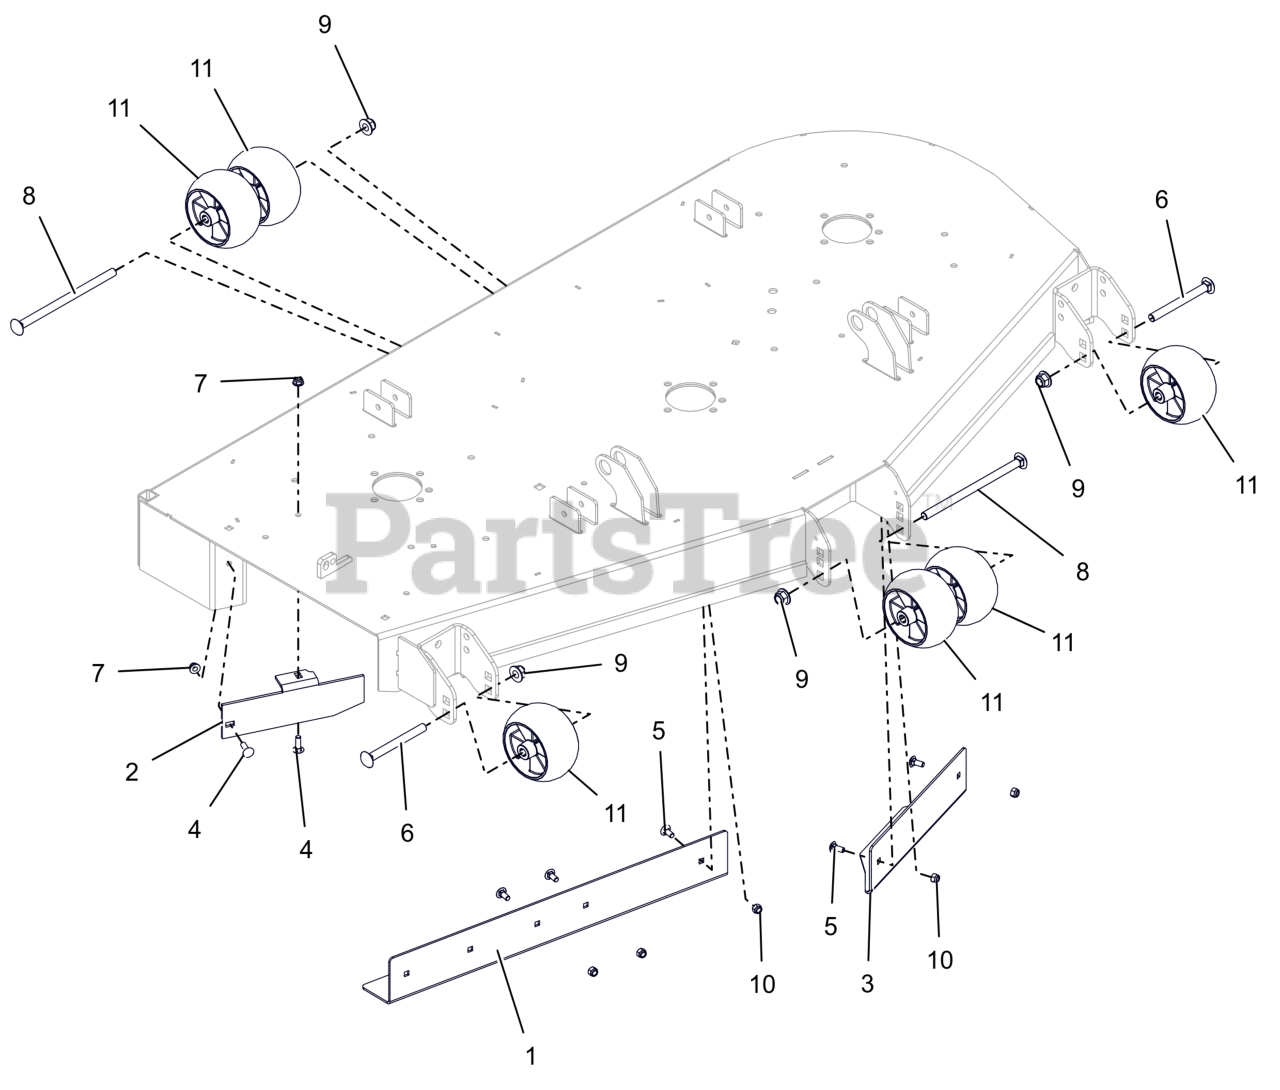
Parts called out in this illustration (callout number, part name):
1	BAFFLE, 60" RH VACUUM (RED)
2	60" DISCHARGE BAFFLE - RED
3	BAFFLE, 60" LH VACUUM (RED)
4	BLT,RHSN .31-18X1.00 G5 ZCC
5	BLT,RHSN .31-18X.75 G5 ZCC
6	BLT, RHSN .50-13X5.00 G5 ZCC
7	NUT,NYL-FLG .31-18 GF ZCC
8	BTL,RHSN .500-13 X 8.5S G5 ZCC
9	NUT,NYL-FLG .50-13 GF ZCC
10	NUT,NYL .31-18 G5 ZCC
11	WHEEL, ANTI SCALP - 5X3 CTR W/RIBS
